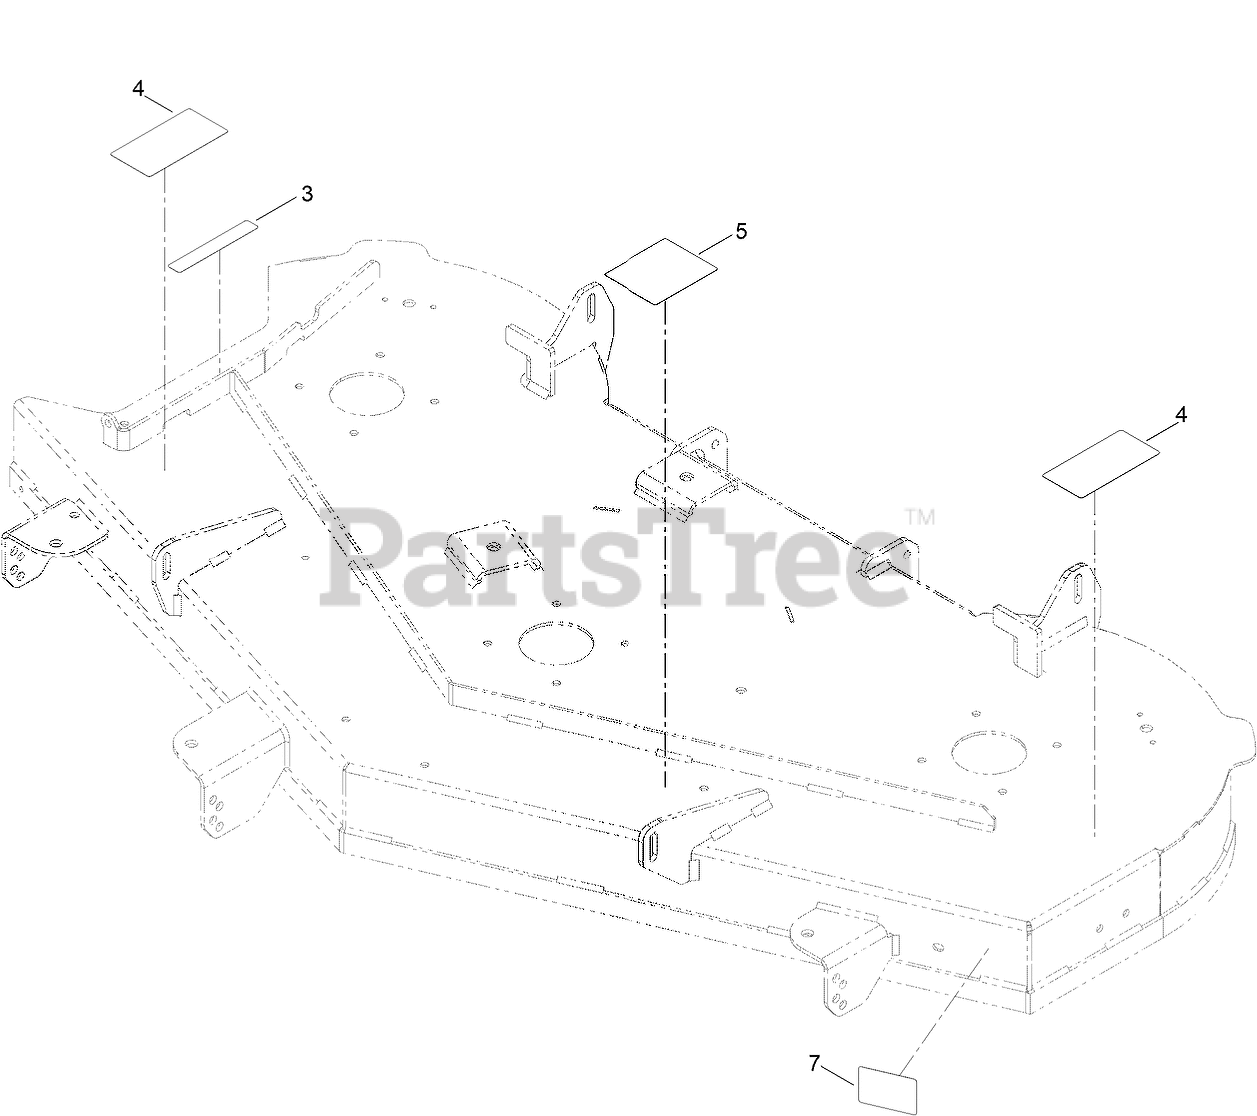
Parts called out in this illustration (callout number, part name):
3	DECAL-DANGER
4	DECAL-DANGER, DECK
5	DECAL-ROUTING, BELT
7	DECAL-SCALP, ANTI
